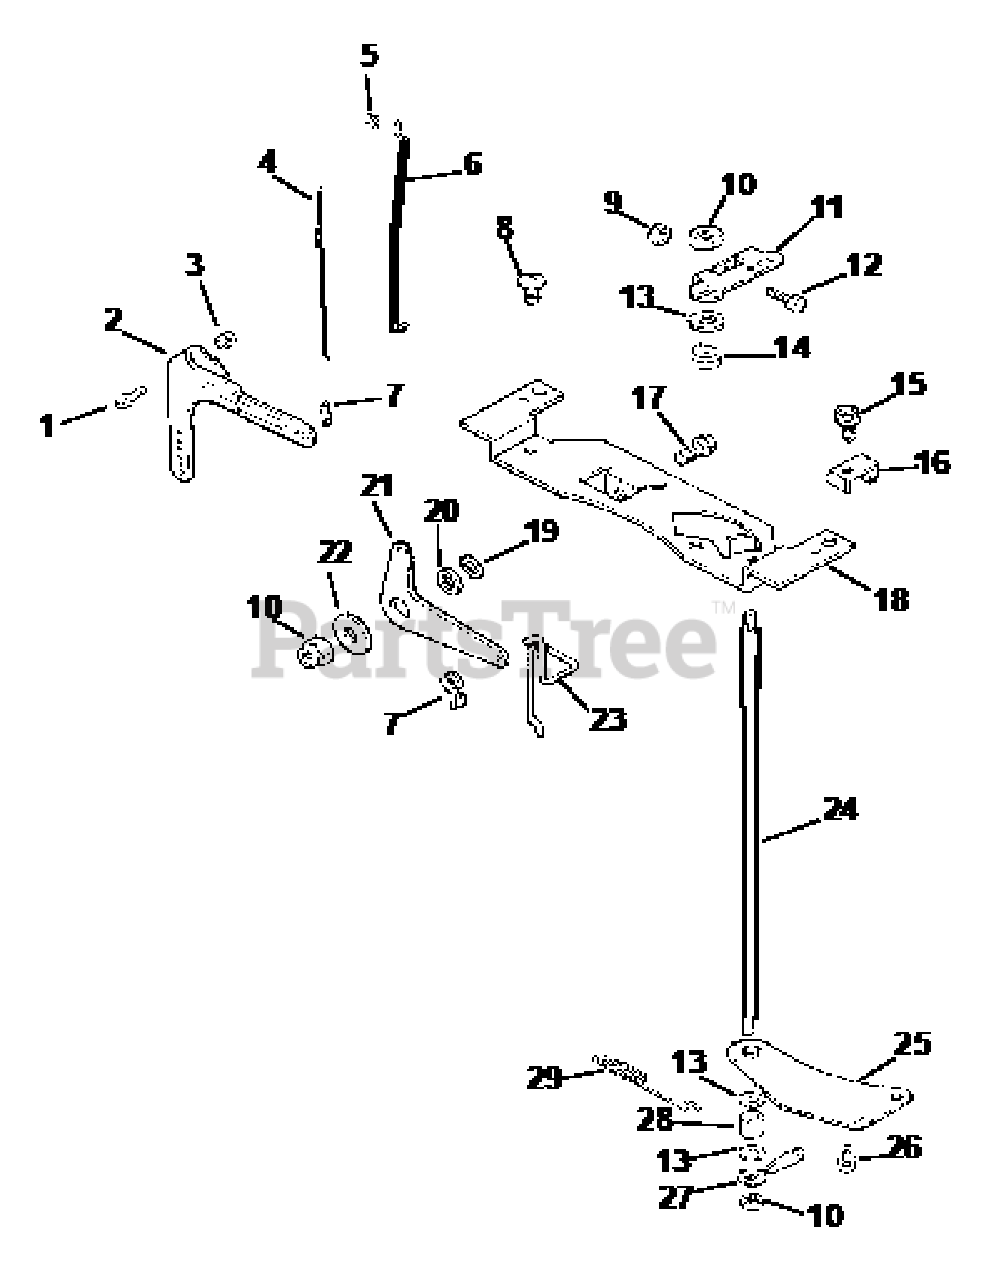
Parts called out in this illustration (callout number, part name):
1	Round Head Sq.Neck Bolt
2	Governor Lever
4	Linkage Spring
5	Linkage Retainig Bushing
6	Throttle Linkage
7	Linkage Retainig Bushing
11	Throttle Control Lever
14	Throttle Shaft Spring
15	Screw
16	Cable Clamp
17	Hex Flange Screw
18	Control Bracket
23	Choke Linkage
24	Throttle Shaft
25	Throttle Shaft Bracket
27	Throttle Control Lever
29	Governor Spring
